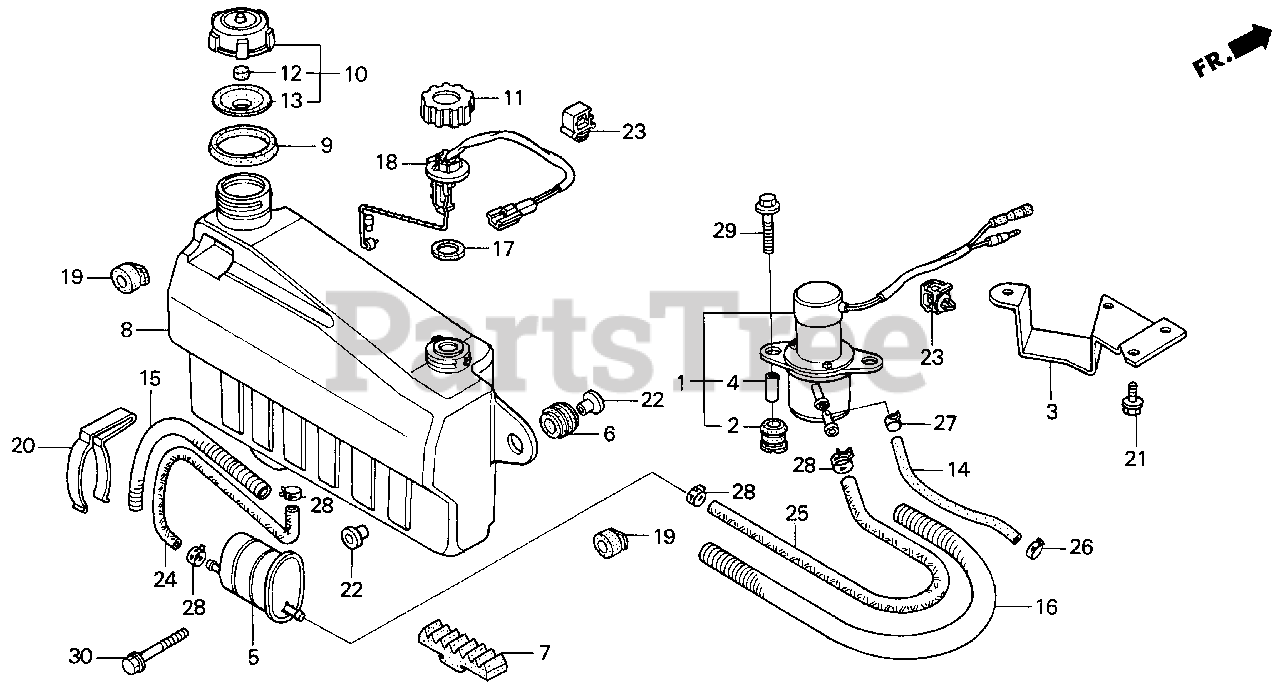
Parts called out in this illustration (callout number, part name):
1	PUMP ASSY., FUEL
2	RUBBER, FUEL PUMP SETTING
3	STAY, FUEL PUMP
4	COLLAR, DISTANCE
5	FILTER, FUEL
6	RUBBER, TANK SETTING
7	RUBBER, TANK CUSHION
8	TANK, FUEL
9	SEAL, FUEL FILLER NECK
10	CAP, FUEL TANK
10	CAP ASSY., FUEL TANK
11	BODY, FUEL CAP
12	SPONGE, FUEL CAP BREATHER
13	GASKET, FUEL CAP
14	TUBE, FUEL SPECIAL
15	TUBE A, CORRUGATED
16	TUBE B, CORRUGATED
17	GASKET, BASE
18	SENSOR ASSY., FUEL RESERVE
19	RUBBER B, BATTERY BOX
20	CLAMP, FUEL STRAINER
21	BOLT, FENDER (6X18)
22	COLLAR, FUEL TANK
23	CLIP, WIRE HARNESS
24	BULK HOSE, FUEL (5.5X8000) (5.5X220)
25	BULK HOSE, FUEL (5.5X8000) (5.5X280)
26	CLIP, TUBE (D8)
27	CLIP, TUBE (D8.5)
28	CLIP, TUBE (D10.5)
29	BOLT, FLANGE (6X30)
30	BOLT, FLANGE (6X35)
